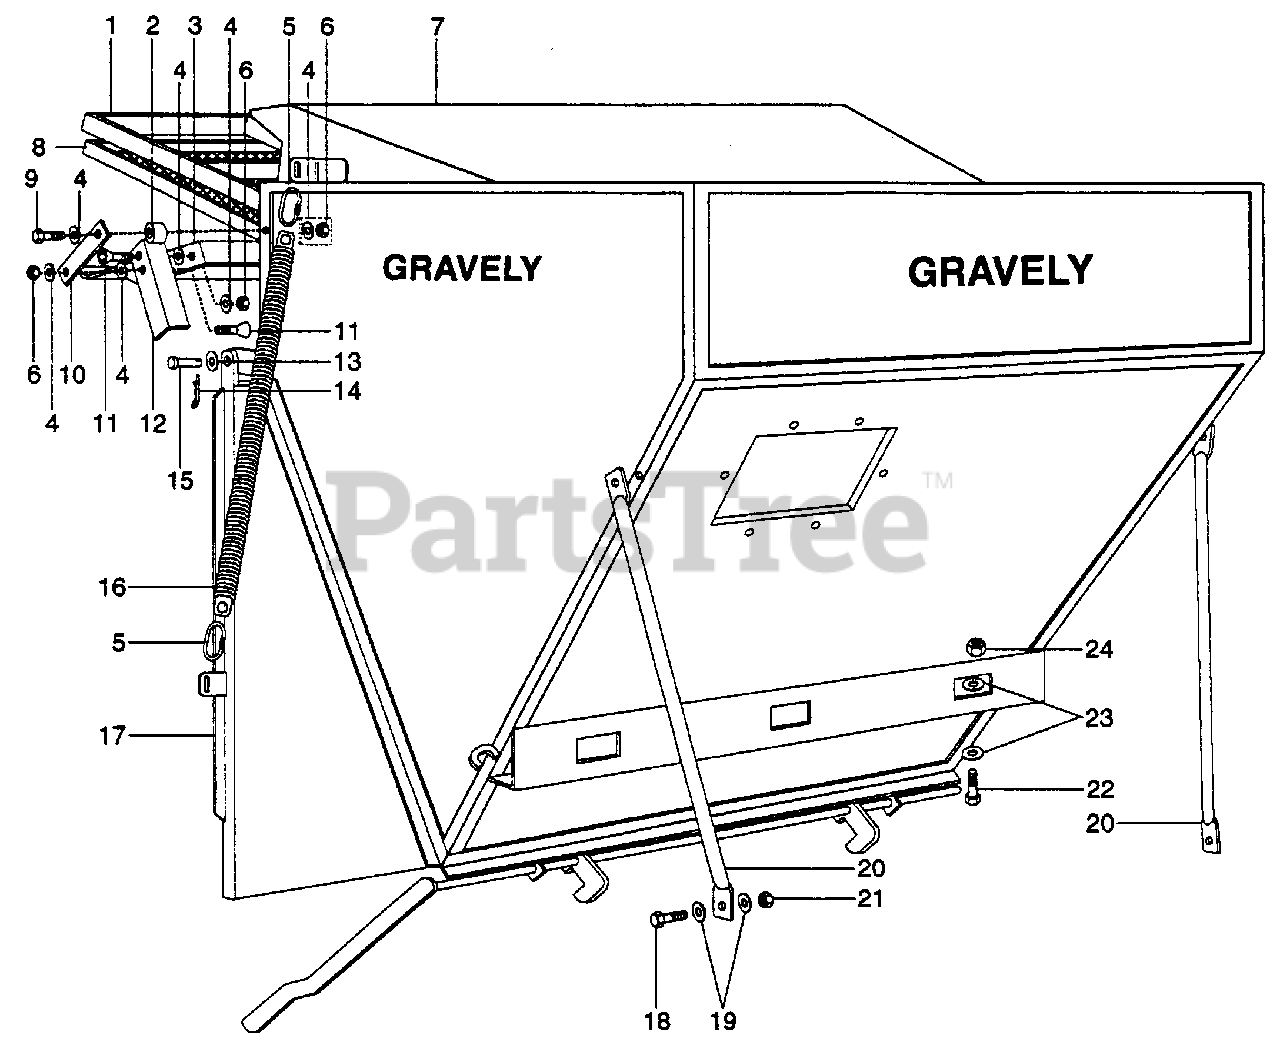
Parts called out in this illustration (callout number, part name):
1	GRID WELDMENT
2	SCREEN DOOR LINK SPACER
3	SCREEN DOOR WELDMENT
4	WSHR-FL-STL .323 X .625 X .062 PL
5	1/4 QUICK LINK
6	NUT-LK-TOP .312-18 GR C PL
7	HOPPER WELDMENT
8	SINGLE SCREEN
9	BLT-HEX .31-18 X 1.50 PL GR 5
10	FILTER DOOR LINKAGE
11	SCR-SKH .31-18 X 1.00 FLTCNTRS
12	FILTER DOOR LATCH RH
12	FILTER DOOR LATCH LH
13	WSHR-FL-STL .406 X .812 X .065 PL
14	PIN-COTR .12 X .75 PL
15	CLEVIS PIN
16	SPRING
17	DOOR WELDMENT
18	BLT-HEX .38-16 X 1.25 PL GR 2
19	WSHR-FL-STL .38 X .875 X .083 PL
20	HOPPER BRACE
21	NUT-LK-TOP .375-16 GR C PL
22	BLT-HEX .50-13 X 1.25 PL GR 5
23	WSHR-FL-STL .511 X 1.45 X .125 PL
24	NUT-LK-CROWN .50-13 GR C
